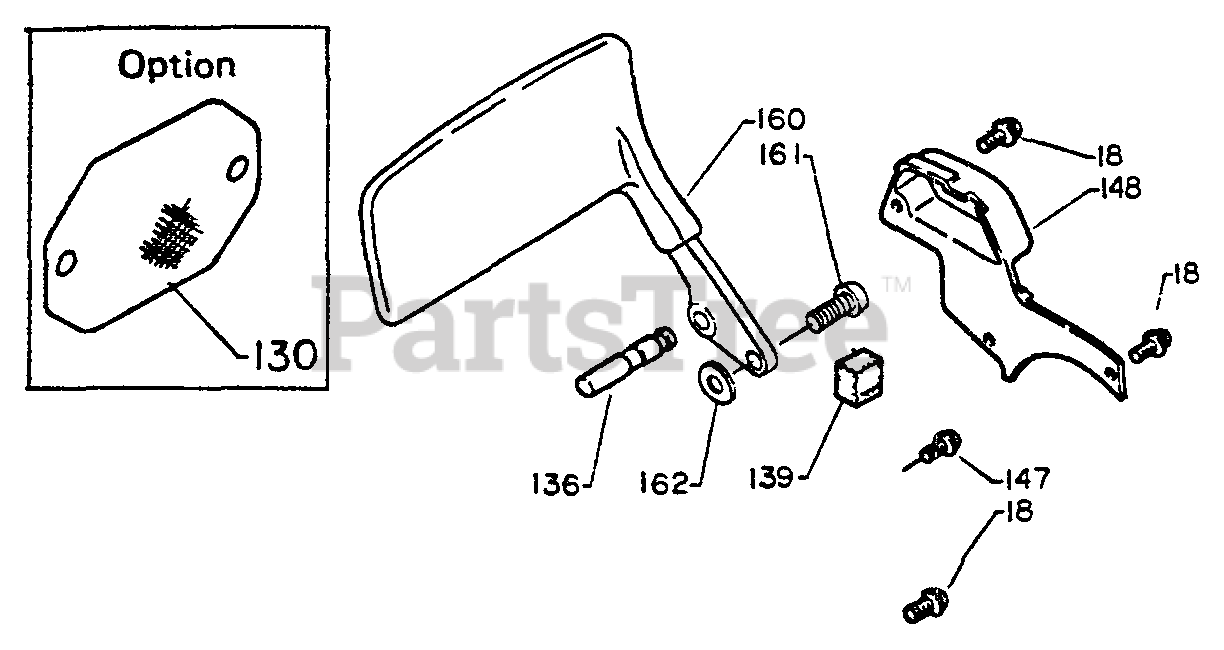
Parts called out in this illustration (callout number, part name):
18	SCREW - 4X12
130	SCREEN, SPARK ARRESTOR
139	SEAL, DUST
147	SCREW - 5X14
148	COVER, BRAKE
160	GUARD
161	SCREW - 6X20
162	WASHER - 6.5
